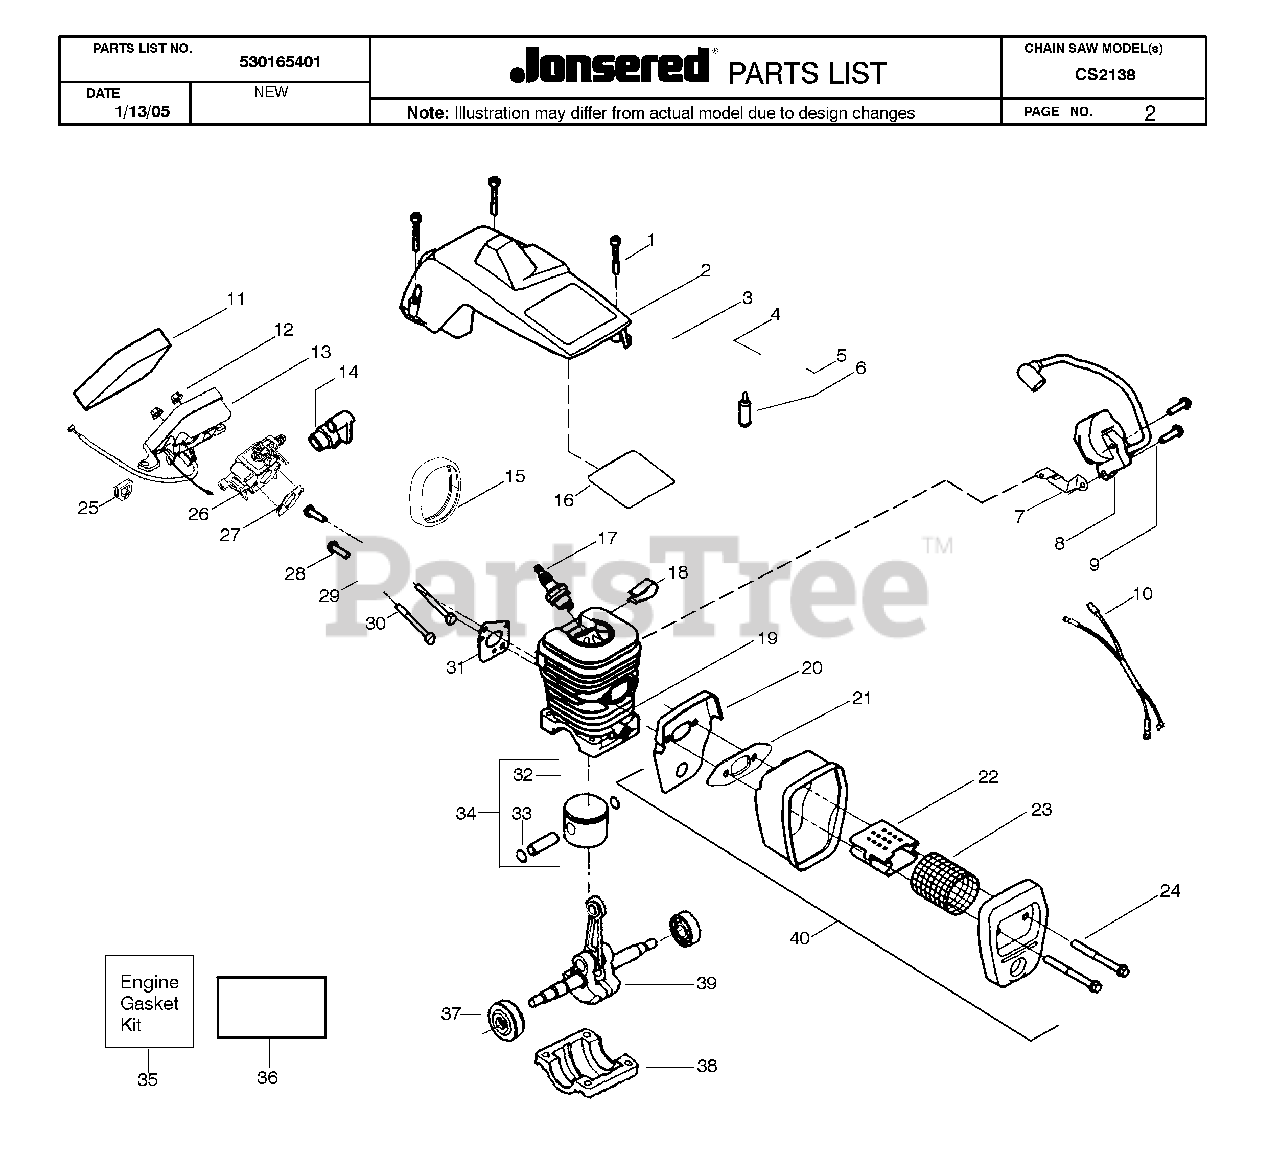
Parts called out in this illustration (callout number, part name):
2	CYL SHIELD ASSY
6	FUEL PICK-UP ASSY
7	GROUND STRAP
10	WIRE HARNESS ASSY
11	AIR FILTER
13	ASSY-AIR BOX
14	GROMMET-CARB ADJUST
17	SPARK PLUG (RCJ-7Y)
22	FLAME PROTECTION
26	CARBURETOR
29	PARTITION
32	RING-PISTON
33	C-CLIP,PSTN PIN 36/41
36	SCRENCH
37	BEARING & SEAL ASSEMBLY
39	CRANKSHAFT
40	MUFFLER
